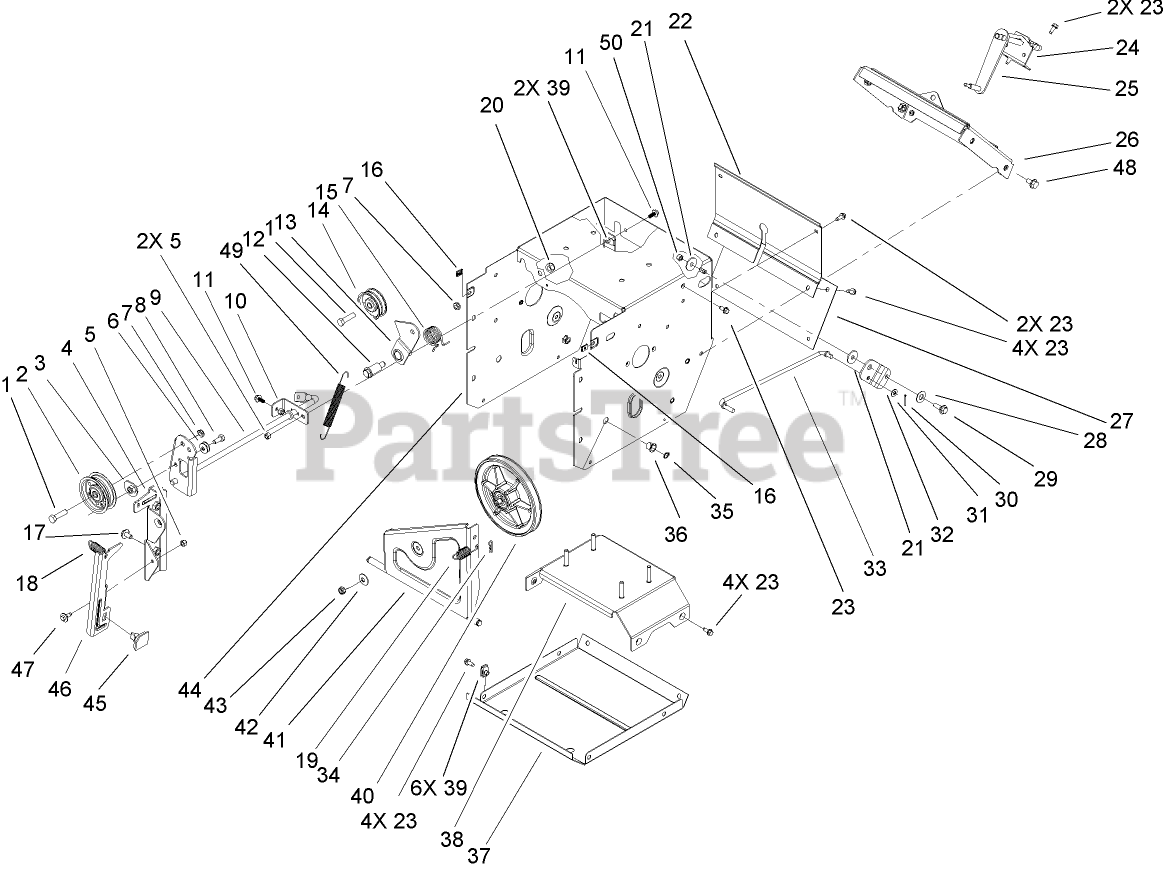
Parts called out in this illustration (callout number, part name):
1	SCREW-HH
2	PULLEY-IDLER
5	NUT-LOCK, NI
6	WASHER-BELLEVILLE
8	SCREW-HH
9	IMPELLER CLUTCH ASM
10	BRACKET-REAR, CLUTCH
11	SCREW-HHF
12	BOLT-SHOULDER
13	ARM-IDLER, TRACTION
14	PULLEY-IDLER
16	NUT-SPEED
17	SCREW-HHF
18	SPRING-EXTENSION
19	SPRING-EXTENSION
20	NUT-LOCK, NI
21	WASHER-PIVOT
22	COVER-UPPER
23	SCREW-HWH
24	BRACKET-ROD, SHIFT
25	LEVER-CONTROL, TRACTION
26	SHIFT PLATE ASM
27	COVER-LOWER
28	WASHER
29	SCREW-SHOULDER
30	PIN-COTTER
31	WASHER-PLAIN
32	BELLCRANK-DRIVE
33	LINK-CONTROL, SPEED
35	RING-RETAINING
36	BUSHING-NYLINER
37	PAN-BOTTOM
40	PULLEY-TRACTION
42	WASHER-BELLEVILLE
43	NUT-HEX
44	TRACTION FRAME ASM
45	PAD-BRAKE
47	SCREW-SHOULDER
48	SCREW-HWHTF
50	NUT-LOCK, NI
